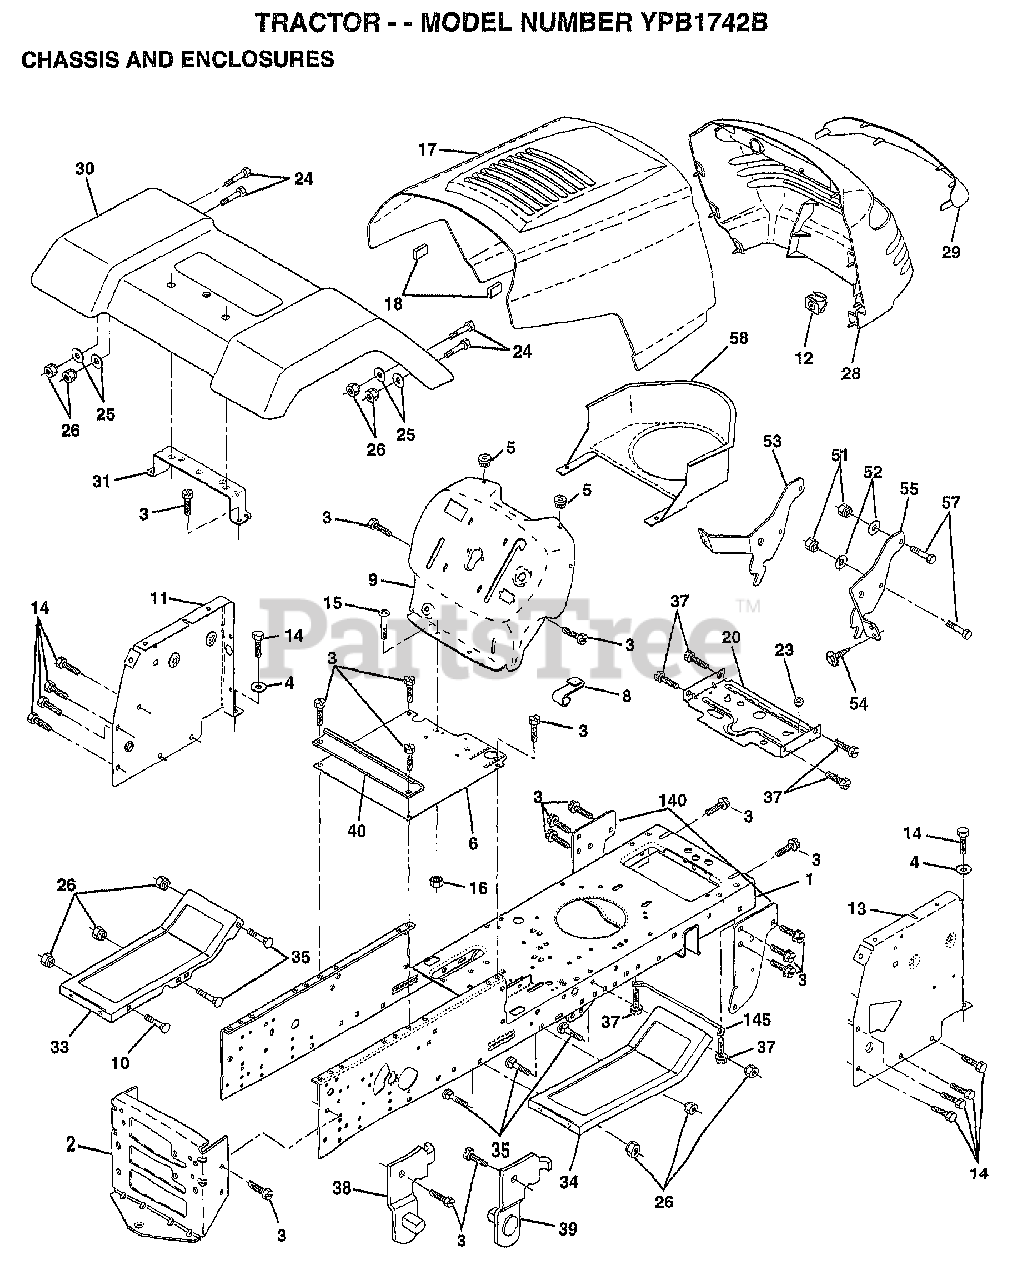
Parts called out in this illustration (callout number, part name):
1	CHASSIS.STAMPING
3	SCREW
4	WASHER
5	BUMPER-HOOD/DASH
6	SADDLE
8	CLIP.RETAINER
9	DASH.SILKSCREEN
11	"PANEL-DASH,LH"
12	CLIP.TINNERMAN
13	"PANEL-DASH,RH"
14	SCREW LT
15	SCREW
17	"HOOD W/TRIM,MS428"
20	"PLATE-MTG,BATT/FU"
24	BOLT
25	WASHER
26	NUT
28	GRILL
29	GRILLE.LENS
30	FENDER.LTST.WLDMNT.W/SHIFT
31	BRACKET SUPT FEND
33	FOOTREST PNT LH
34	FOOTREST.RH.LT/GT
35	BOLT
37	SCREW LT
38	BRACKET ASM LH
39	BRACKET ASM RH
40	SPACER FENDER LT
51	NUT
52	WASHER
53	BRACKET.GRILLE.LH
54	SCREW.HEX.WS.HD
55	BRACKET.GRILLE.RH
58	AIR DUCT
140	BRKT SUSPENSION
145	"ROD POVOT,CHASSIS"
